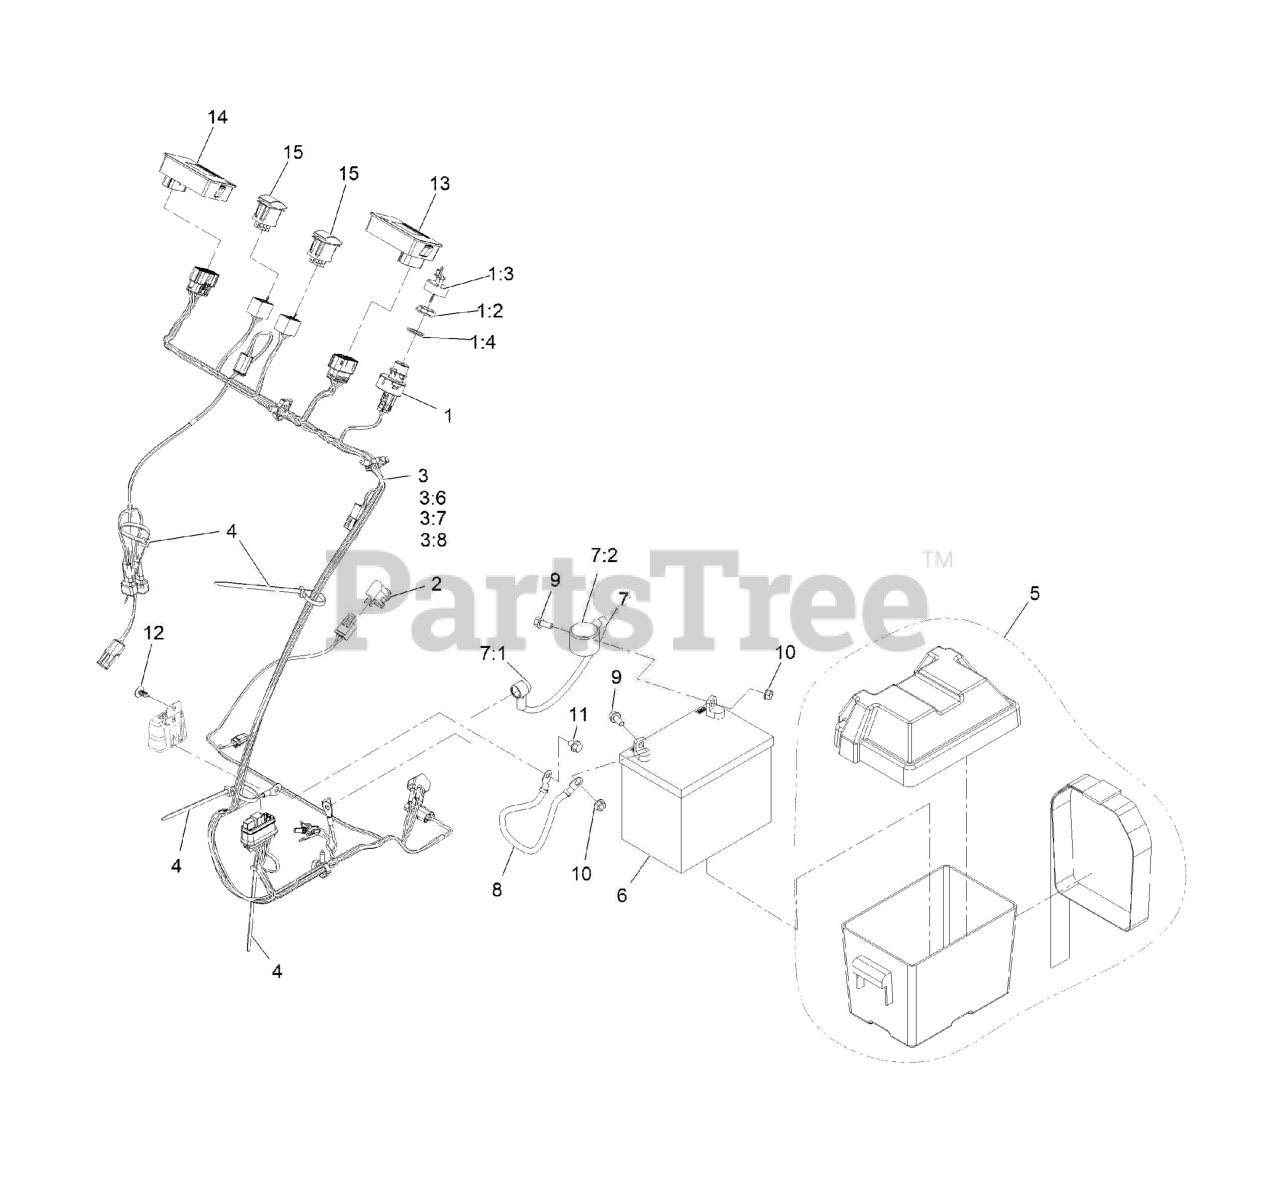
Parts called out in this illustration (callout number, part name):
1	IGNITION SWITCH ASM
1:2	NUT-MOUNTING
1:3	IGNITION KEY SET
1:4	WASHER-BACKUP
2	SWITCH-BAIL
3	Harness-Wire
3:6	FUSE-MINI BLADE, 20 AMP
3:7	RELAY-MICRO
3:8	Relay-Coil, NC, Mp280
4	TIE-CABLE
5	BATTERY BOX
6	Battery
7	Positive Battery Cable ASM
7:1	INSULATOR-SOLENOID
7:2	INSULATOR-BATTERY
8	CABLE-BATTERY, NEGATIVE
9	SCREW-HHF
11	Screw-HHF
12	PLUG-PLASTIC
13	Hour Meter ASM
